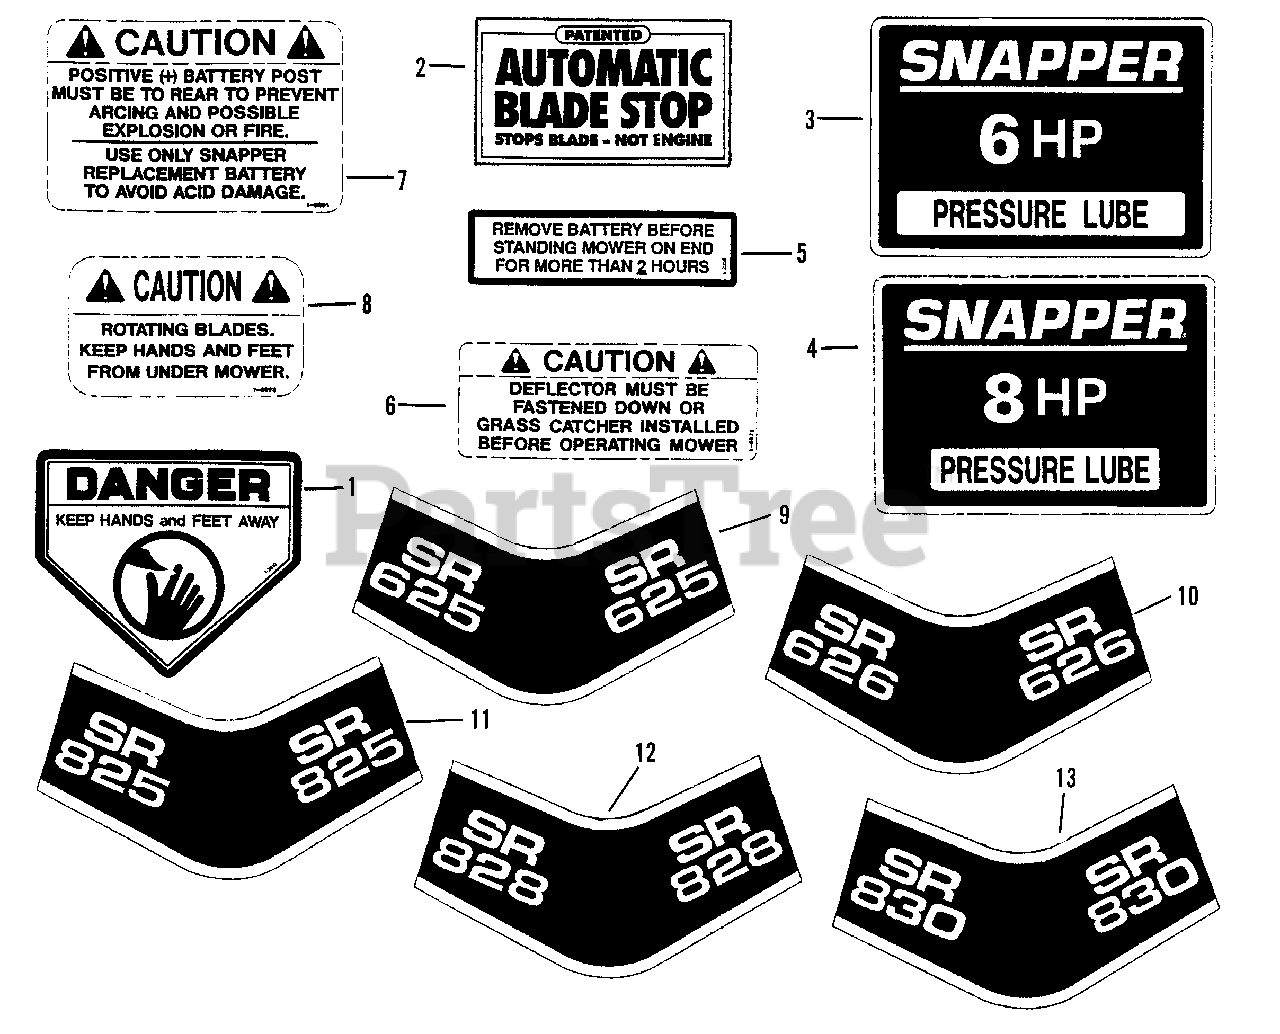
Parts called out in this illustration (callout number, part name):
1	DECAL, Danger
2	DECAL, Auto Blade Stop
3	DECAL, 6 HP Pressure Lube
4	DECAL, 8 HP Pressure Lube
5	DECAL, Battery Storage
6	DECAL, Caution Deflector
7	DECAL, Caution Battery
8	DECAL, Caution Rotating Blades
9	DECAL, SR625
10	DECAL, SR626
11	DECAL, SR825
12	DECAL, SR828
13	DECAL, SR830
